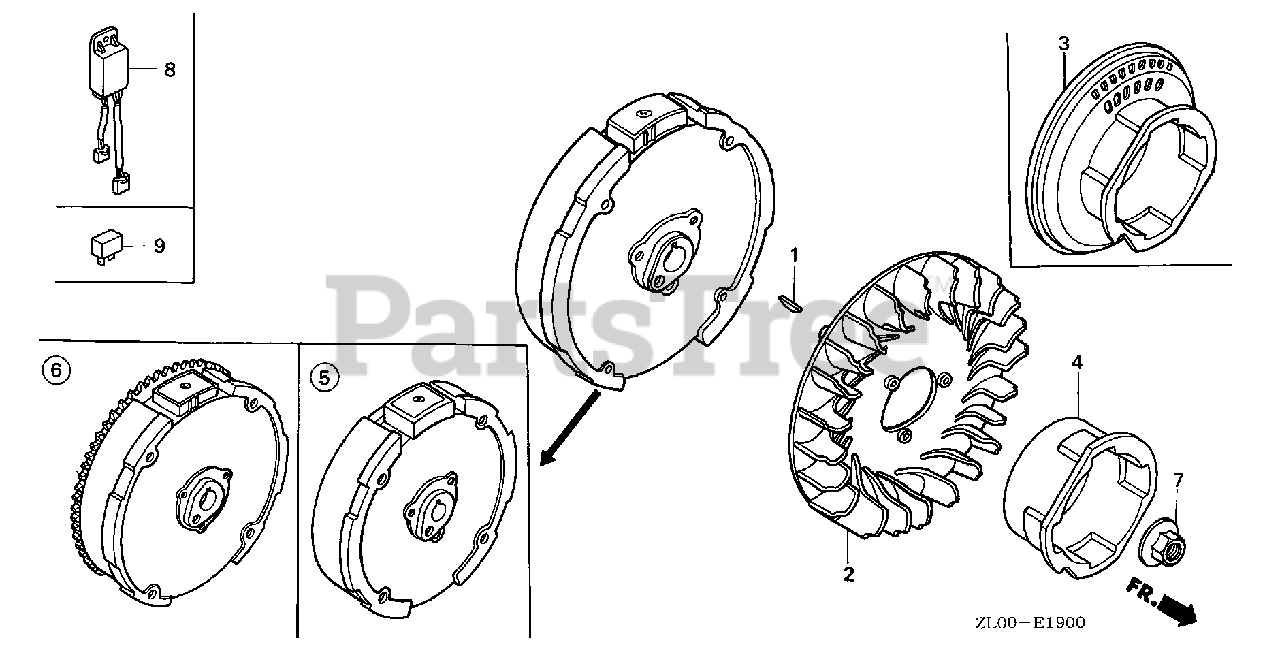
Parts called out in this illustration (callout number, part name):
1	KEY, SPECIAL WOODRUFF (25X18)
2	FAN, COOLING
4	PULLEY, STARTER
5	FLYWHEEL (STD)
7	NUT, SPECIAL (14MM)
